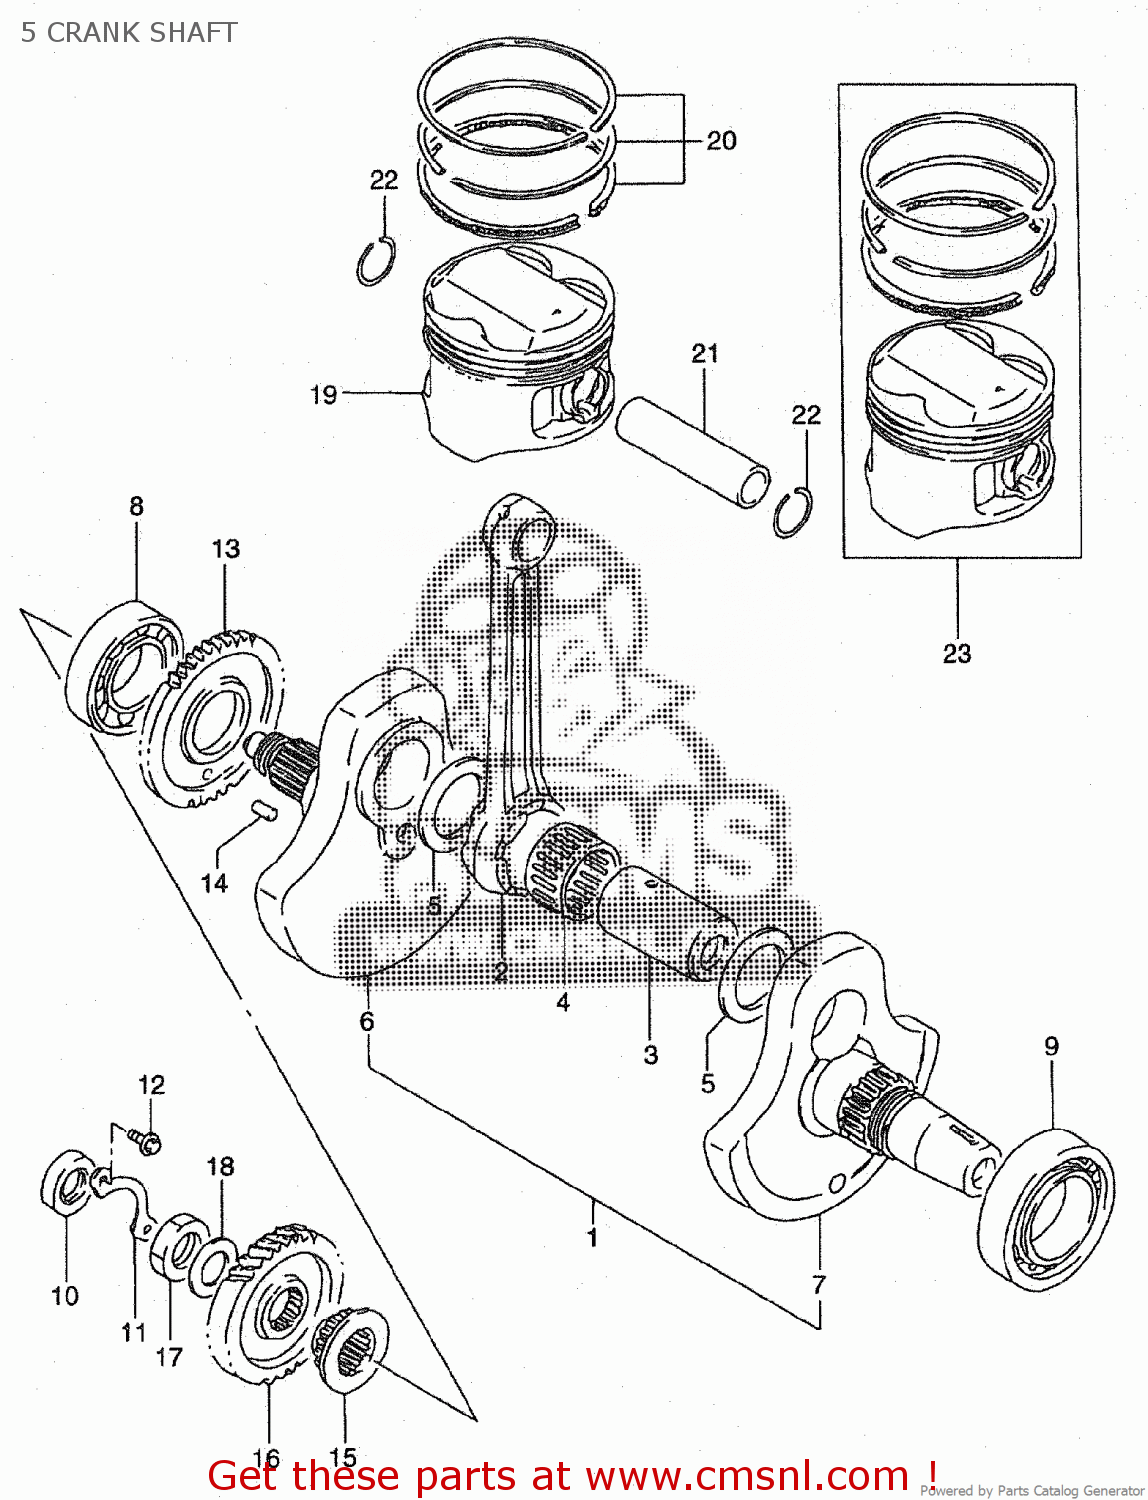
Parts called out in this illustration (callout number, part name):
2	CONNECTING ROD
4	BEARING(34X43X22)
5	WASHER(34X52X1)
8	BEARING(35X72X17)
9	BEARING(40X80X18)
10	SEAL,OIL(16X30X6)
11	RETAINER,CRANKSHAFT OIL SEAL,R
12	BOLT
13	GEAR,CRANK BALANCER DRIVE
14	PIN
15	SPROCKET,CAM CHAIN DRIVE
17	NUT (20MM)
18	WASHER
20	RING SET,PISTON
21	PISTON PIN
22	RING,SNAP
